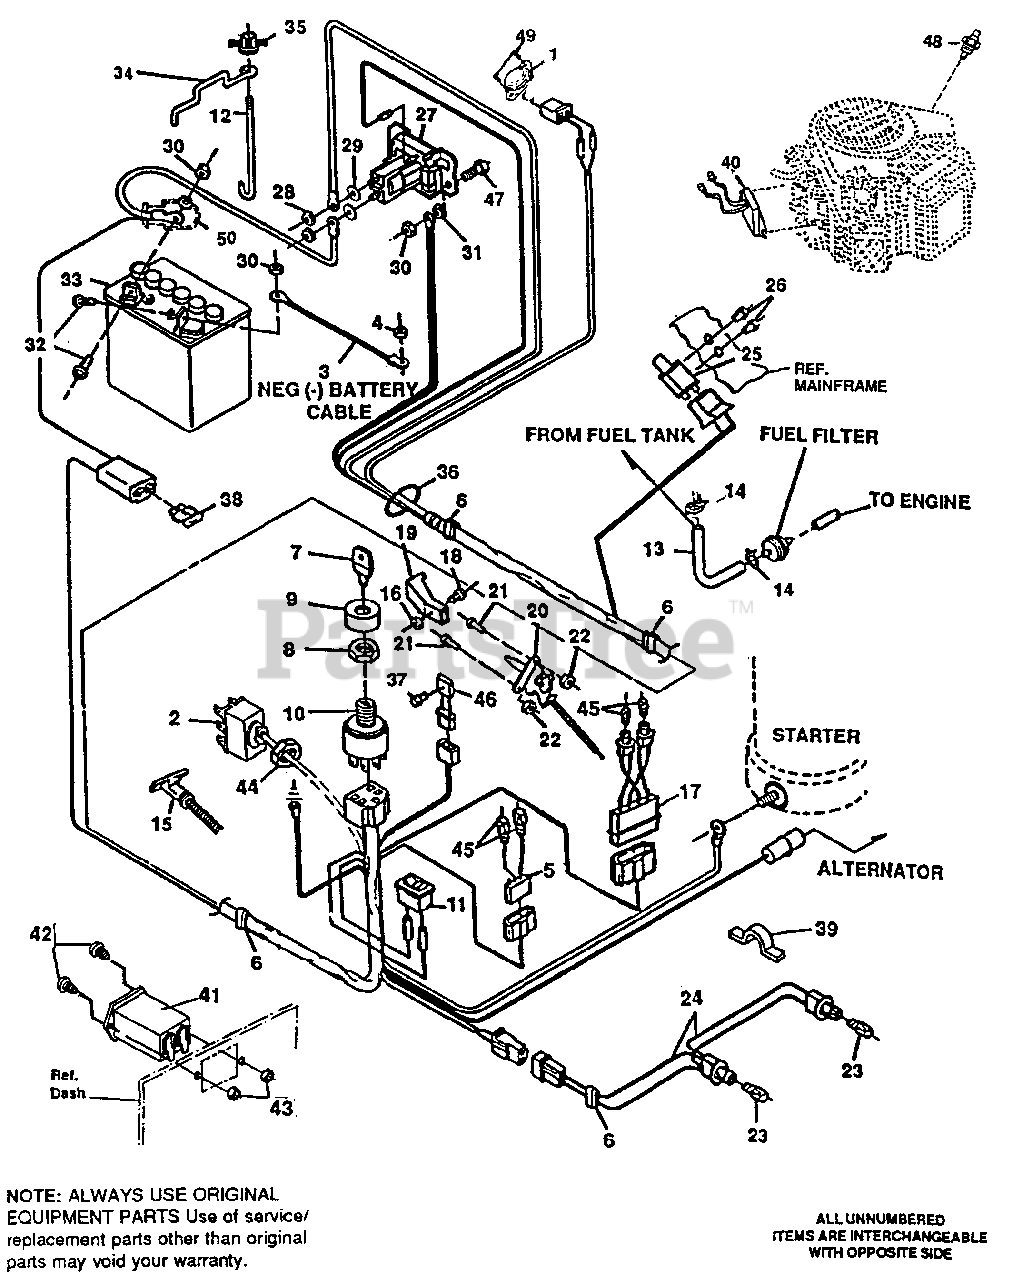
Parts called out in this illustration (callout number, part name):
1	Seat Switch
2	Switch, Elec/Clutch Actuator
3	Cable, Battery, Negative
4	Nut, Hx, Keps, 5/16-18 Thd.
5	4-Pin Lampholder
6	Tie Cable
7	Key, Ignition Switch
8	Nut, Switch
9	Boot, Switch
10	Switch, Ignition
11	Switch, Light
12	Rod, Battery Hold-Down
13	Gas Line, 10" (cut to length)
14	Clamp, Gas Line
15	Choke Control
16	Nut, Hex, #8-32 Thd.
17	3-Pin Lampholder
18	Screw, Ph Pn, #8-32 x 3/8 In.
19	Knob, Throttle Control
20	Throttle Control
21	Screw, #10-24 X 5/8 In.
22	Nut, Hx, Nylon Lock, #10-24 Thd.
23	Bulb Headlamp
24	Assembly, Light Wire
26	Screw, Pn Hd, Tap #12 x 1/2 In.
27	Solenoid
28	Nut, Hx 5/16-24 Thd.
29	Washer, Lock 5/16 In.
30	Nut, Hx, Keps, 1/4-20 Thd.
31	Nut, Hx, Ctrlk, 1/4-20 Thd.
32	Screw, 1/4-20 x .63
34	Bracket, Battery Hold-Down
35	Wingnut, 1/4-20 Thd.
36	Wiring Harness
37	Plastite Screw
38	Fuse, 15A-32V
39	Press Clip
40	Regulator, Sen Volt B & S With Sensor
41	Miniature Hour Meter
42	Screw, #6-32 x 1/2 In.
43	Nut, #6-32
45	Indicator Bulb
46	Voltage Sensor
47	Screw, 1/4-20 x .75
48	Oil Sensor, B & S. Twin Cycle
49	Screw, 1/4-20 x .38
50	Boot, Rubber (battery cable)
